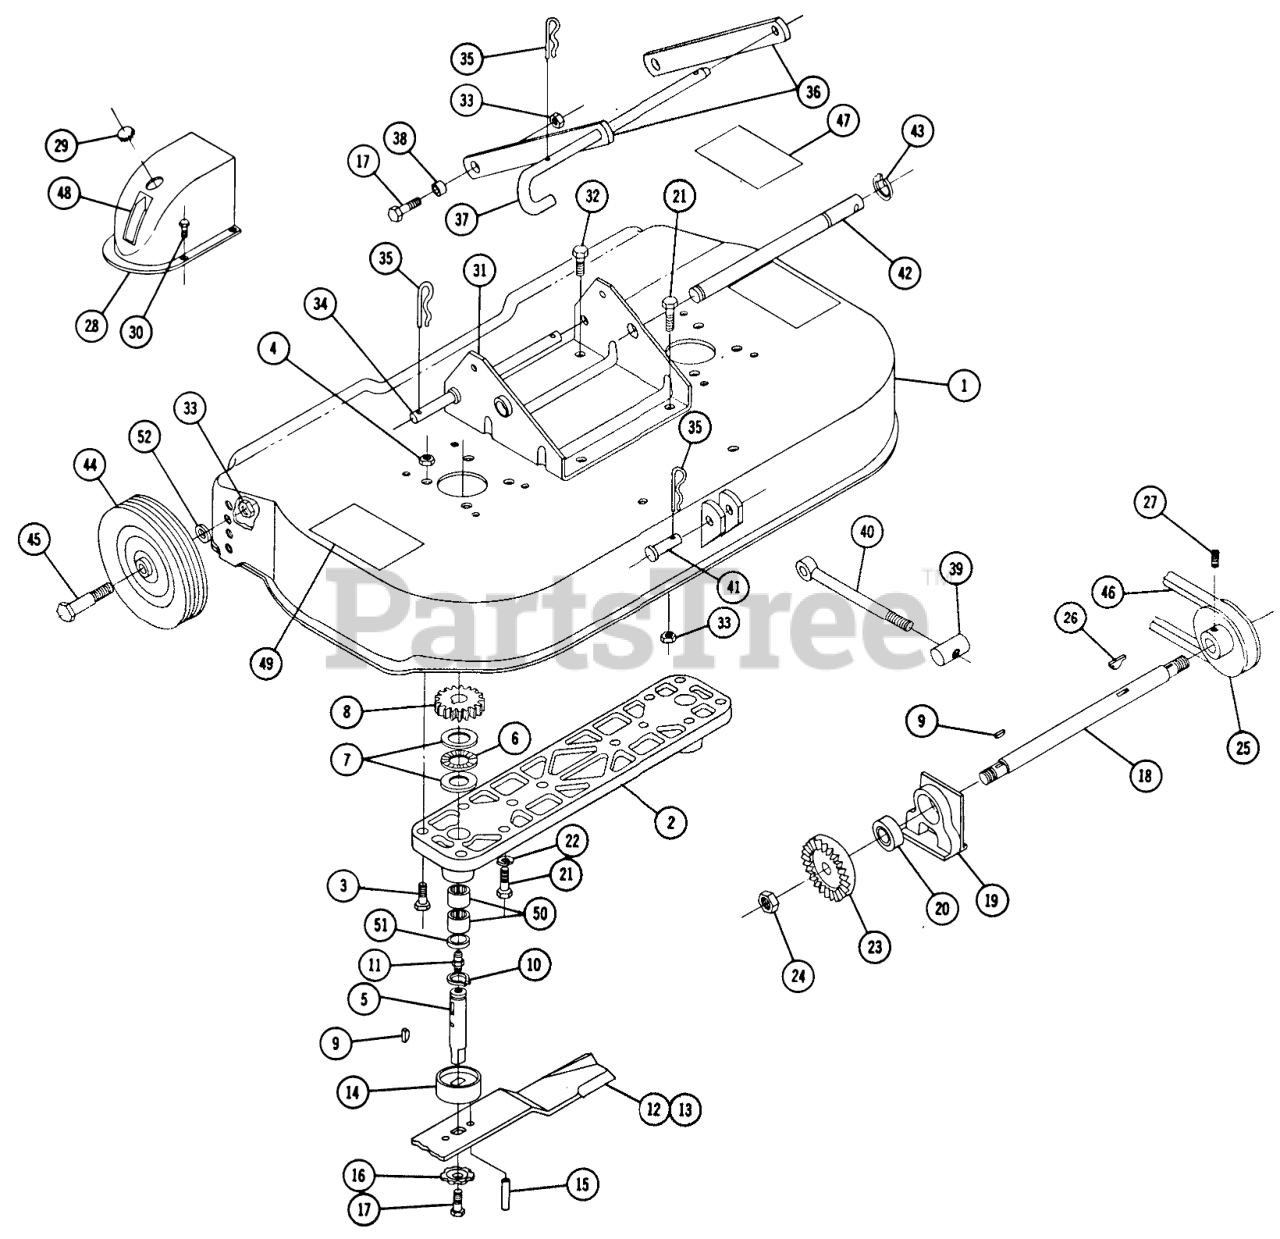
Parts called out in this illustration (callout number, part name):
1	Ass-y. Deck
3	Bolt 5/16-18 x
4	Nut-Nylok
7	WASHER-THRUST
15	SPIROL ROLL PIN
17	Bolt 3/8-16 x 7/8
19	BEARING SUPPORT
21	Bolt 3/8-16 x 1
22	Lockwasher
27	Set Screw 5/16-18 x 5/16
29	PLUG BUTTON
30	SCREW
31	Hanger
32	Bolt 3/8-16 x 3/4
33	3/8-16 E.S.
34	Pin
35	Hairpin
41	Pin-Clevis
42	Shaft-Belt Tightener
43	E-RING
45	BOLT-SHOULDER
46	V BELT
47	Decal-Belt Diagram
48	Decal
52	Washer 3/8
